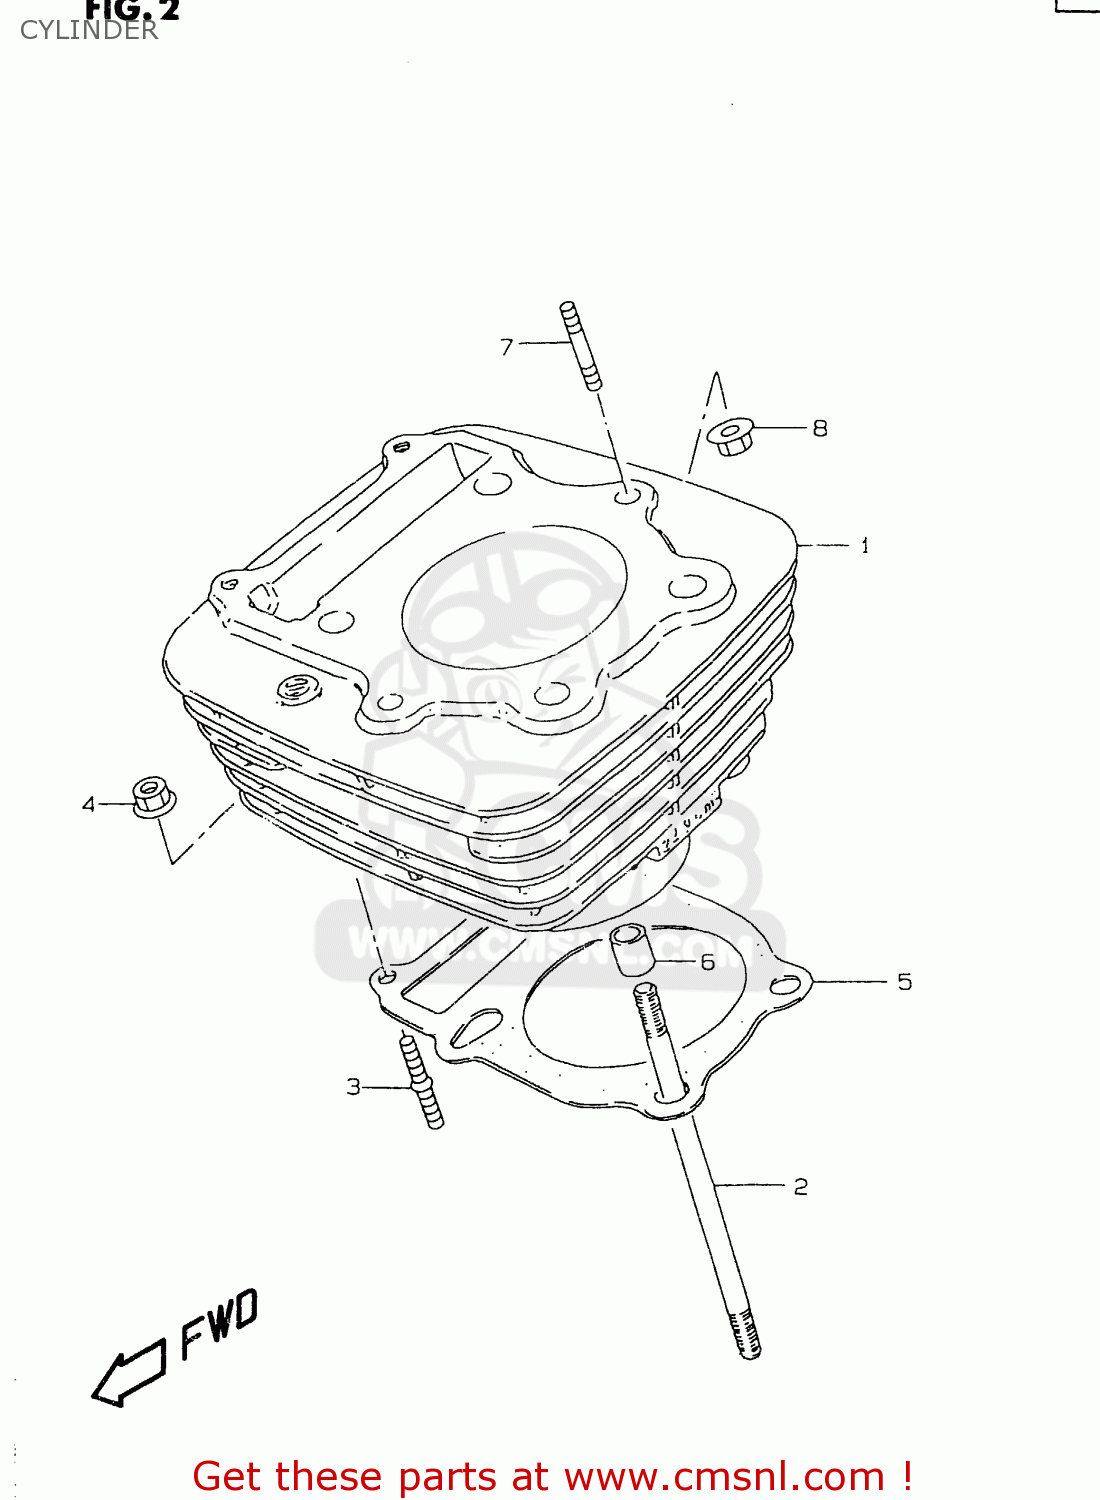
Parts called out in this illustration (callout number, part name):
1	CYLINDER
2	BOLT,STUD
3	STUD 6X20
4	NUT
5	GASKET,CYLINDER (NAS)
6	PIN
7	BOLT,STUD
8	NUT
